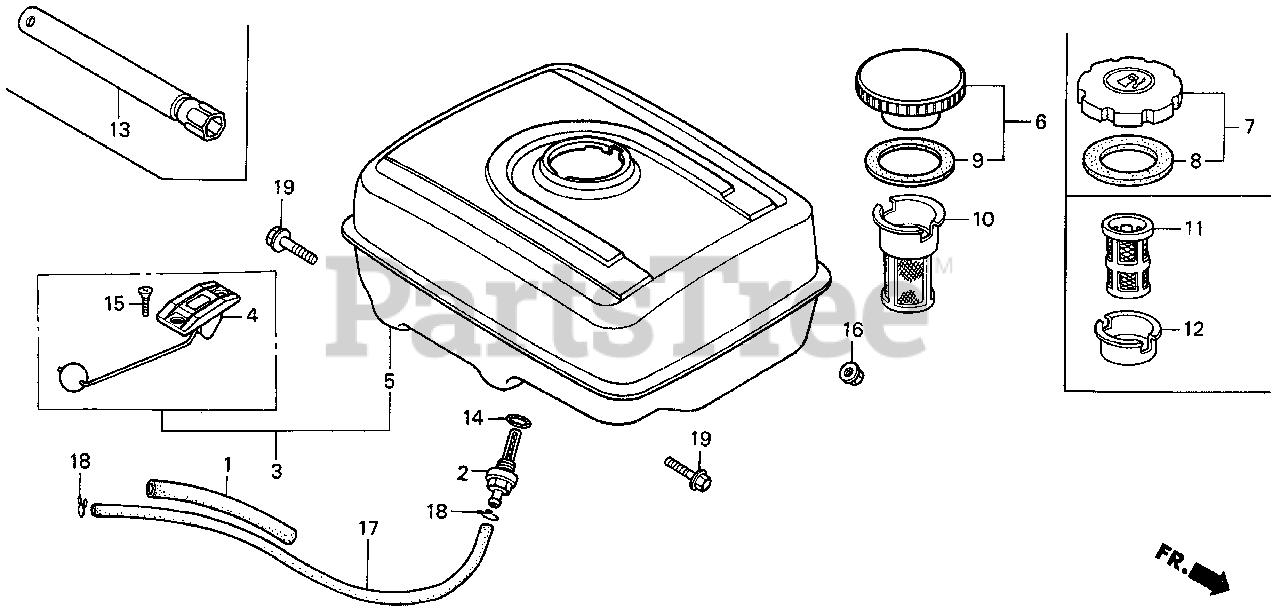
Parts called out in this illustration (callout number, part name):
1	RUBBER, SUPPORTER
1	RUBBER, SUPPORTER (107MM)
2	JOINT, FUEL TANK
5	TANK, FUEL *NH31* (MCKINLEY WHITE)
5	TANK, FUEL *NH105* (MAT BLACK)
6	CAP, FUEL FILLER
7	CAP, FUEL FILLER
8	GASKET, FUEL FILLER CAP
9	GASKET, FUEL FILLER CAP
10	FILTER, FUEL
11	FILTER, FUEL
12	HOLDER, FUEL FILTER
13	WRENCH, SPARK PLUG
14	O-RING (13.5X1.5) (ARAI)
16	NUT, FLANGE (8MM)
17	BULK HOSE, FUEL (4.5X3000) (4.5X222)
18	CLIP, TUBE (B8)
19	BOLT, FLANGE (8X25)
